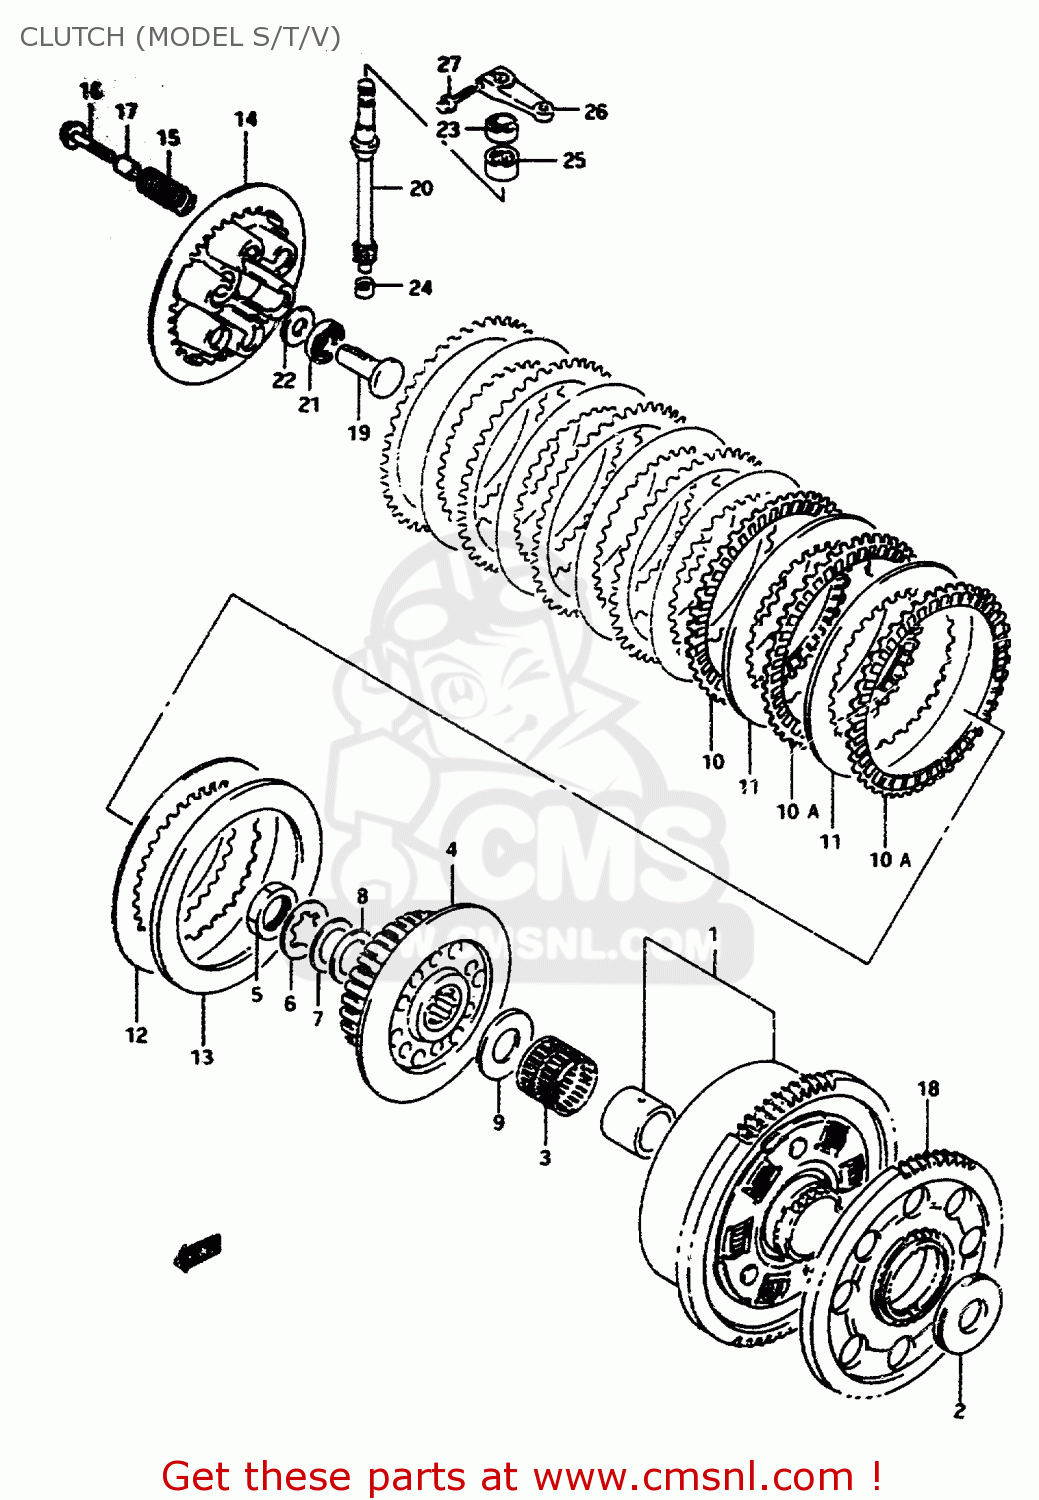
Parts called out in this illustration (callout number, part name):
1	GEAR ASSEMBLY,PRIMARY DRIVE
2	WASHER(25X54X2.5)
3	BEARING(35X40X35.8)
4	HUB,CLUTCH SLEEVE
5	NUT
6	WASHER,LOCK
7	WASHER
8	WASHER
9	WASHER(25X50X2.5)
10	PLATE,CLUTCH DRIVE
10A	PLATE,CLUTCH DRIVE (NAS)
11	PLATE,CLUTCH DRIVEN
12	PLATE,CLUTCH DRIVEN (NAS)
13	SPACER,CLUTCH PLATE
14	DISC,CLUTCH PRESSURE
15	SPRING
16	BOLT(6X40)
17	SPACER(6.4X10X28)
18	GEAR,GENERATOR DRIVE
19	RACK,CLUTCH RELEASE
20	PINION,CLUTCH RELEASE
21	BEARING(15X28X2)
22	WASHER(15.5X28X1)
23	OIL SEAL
24	BEARING 10X14X10
25	BEARING(15X22X12)
26	ARM,CLUTCH RELEASE
27	BOLT
